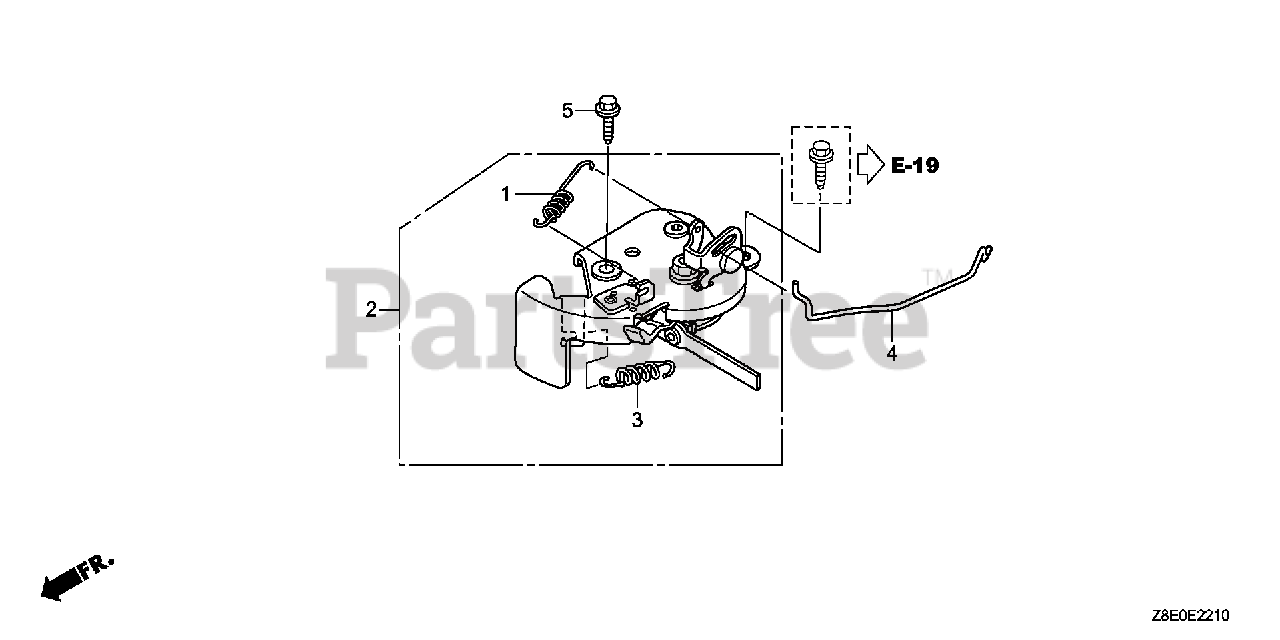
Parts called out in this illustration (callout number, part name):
1	SPRING, RETURN
2	LEVER ASSY., CHOKE
3	SPRING, CHOKE LEVER
5	BOLT, FLANGE (6X20) (CT200)
